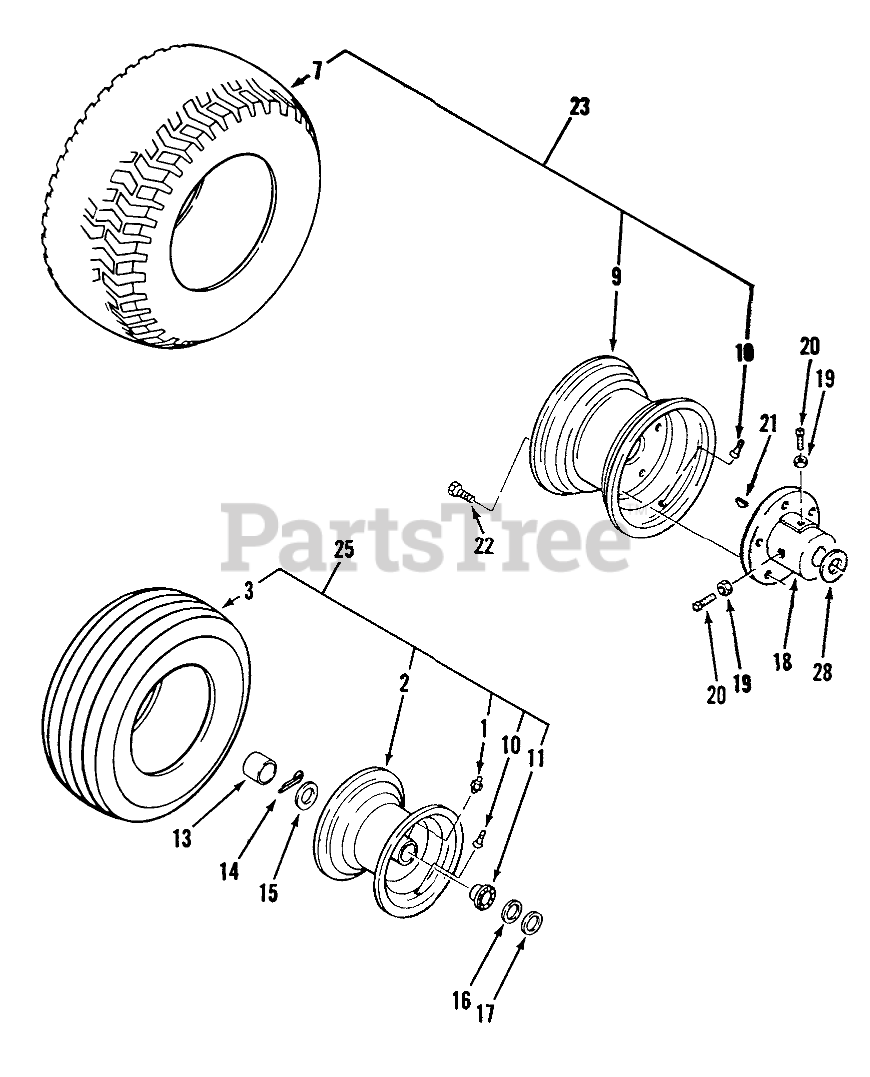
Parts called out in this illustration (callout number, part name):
1	ZERK-GREASE
2	Front Wheel (includes items 1, 10 & 11)
3	TIRE TURF SAVER 16X6.50-8
7	Engine
9	WHEEL
10	VALVE
11	BEARING-WHEEL
13	HUBCAP
14	COTTER PIN-4
15	WASHER WHEEL
16	WASHER
17	WASHER-SHIM
18	Hub Rear
19	Nut
20	Screw-Set
21	KEY-WOODRUFF
22	Lug Nut
23	Rear Wheel & Tire Assy 416
25	Front Wheel & Tire Assy 414, 416
28	WASHER-THRUST
